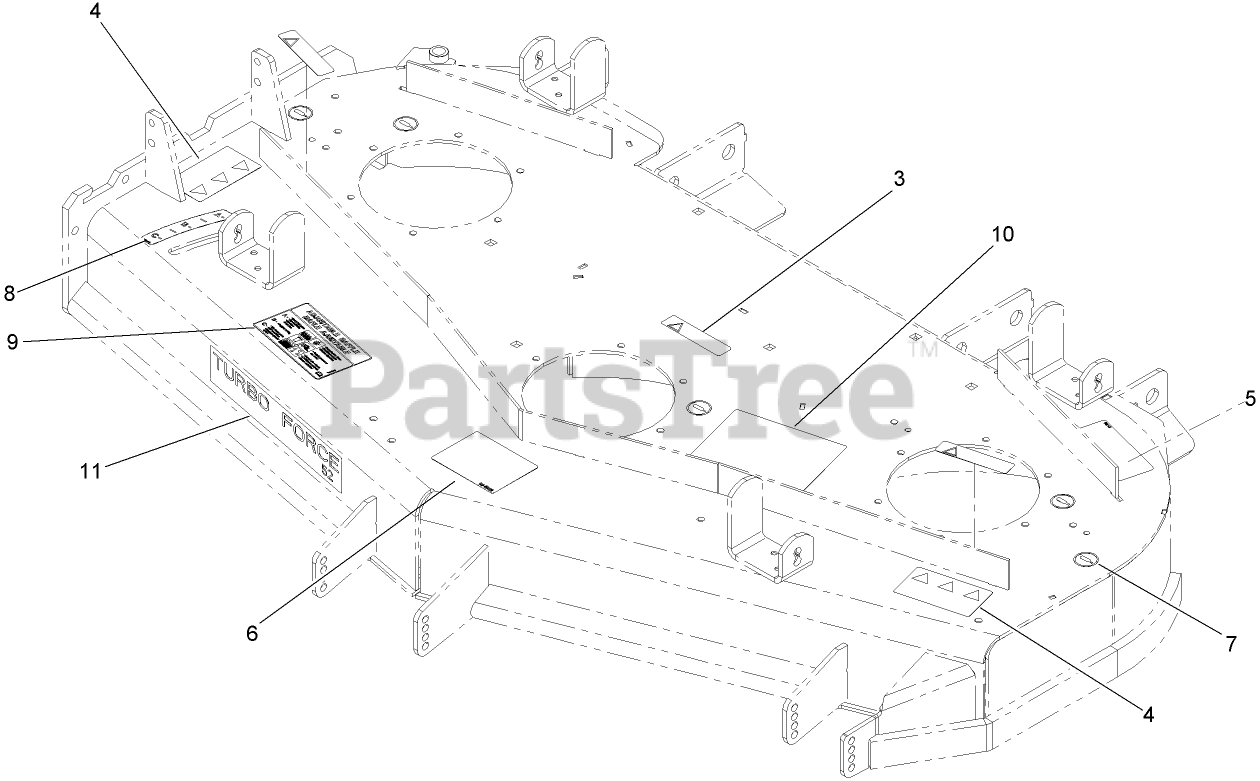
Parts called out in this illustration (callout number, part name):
3	DECAL-WARNING
4	DECAL-DANGER
5	DECAL-TORQUE, BLADE BOLT
6	DECAL-ANTI SCALP
7	DECAL-GREASE
8	DECAL-SETTING, BAFFLE
9	DECAL-ADJUSTMENT, BAFFLE
10	DECAL-SERVICE AID
